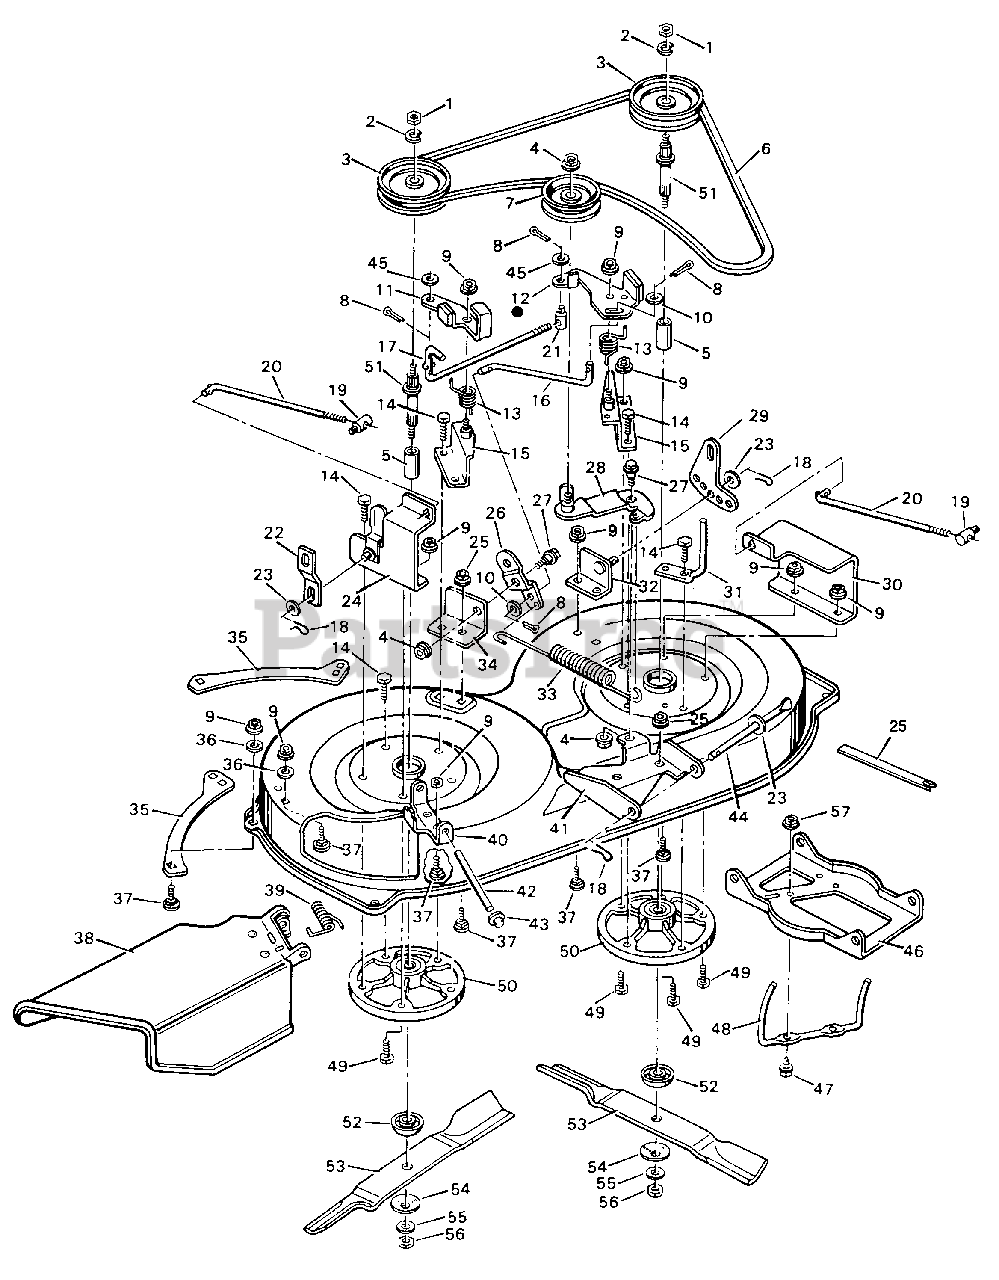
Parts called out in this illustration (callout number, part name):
1	NUT- Centerlock
2	WASHER- Lock
3	PULLEY- Jackshaft
4	NUT- Lock (flange)
6	BELT- Blade drive
7	PULLEY- Idler
8	PIN- Cotter
9	NUT- Lock (flange)
10	WASHER
11	BRAKE ASSEMBLY (Right)
12	BRAKE ASSEMBLY (Left)
13	SPRING- Torsion
14	BOLT- Hex
15	BRAKE BRACKET ASSEMBLY
16	BRAKE ROD
17	ROD- Cross link
18	PIN- Hair
19	NUT- Adjustable
20	ROD- Adjuster
21	NUT- Adjustable
22	LINK- Suspension
24	RIGHT LIFTER BRACKET ASSY.
25	INDICATOR- Plastic
26	BRACKET- Pivot
27	BOLT- Carriage
28	IDLER ARM ASSEMBLY
29	PLATE- Adjuster
30	COVER- Pulley
31	GUIDE- Belt
32	LEFT LIFTER BRACKET ASSY.
33	SPRING- Extension
34	BRACKET- Pivot
36	WASHER
37	BOLT- Carriage
38	CHUTE DEFLECTOR ASSEMBLY
39	SPRING- Torsion
40	BRACKET- Hinge
41	BRACKET- Front hanger
42	ROD- Deflector
43	CAP- Push on
44	ROD- Hanger
46	HANGER- Front
48	GUIDE- Belt
49	BOLT- Hex
50	HOUSING- Spindle
52	ADAPTER- Blade
53	BLADE
54	WASHER- Belleville
